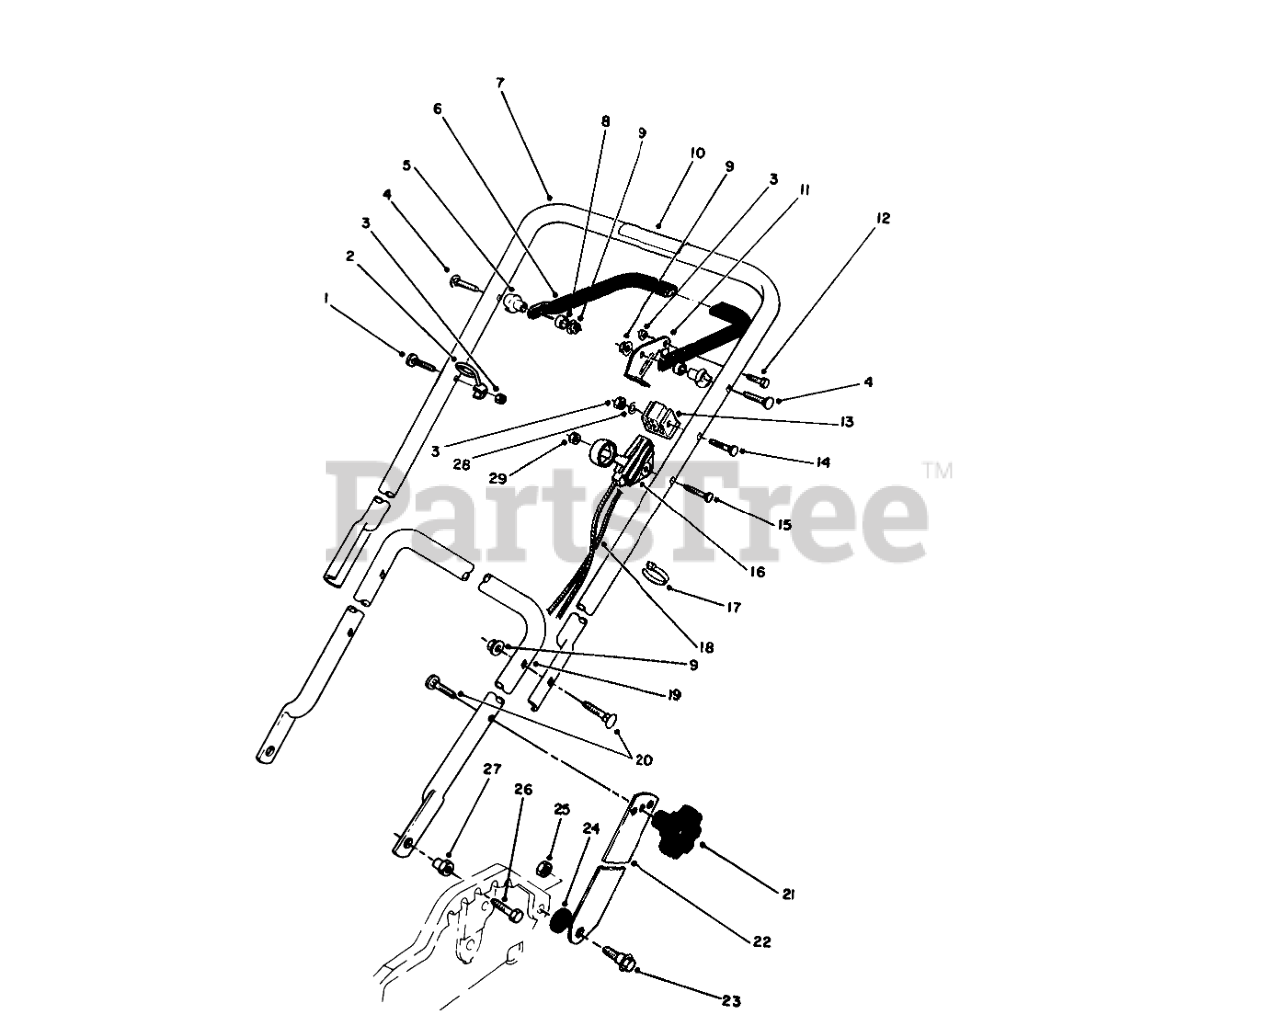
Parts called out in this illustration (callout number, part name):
1	HANDLE SCREW
2	Guide
3	NUT-LOCK, NI
4	5/16-18 X 2 HNDLE SCREW
5	SPACER-SUPPORT
6	Bar-Control
7	Handle-Upper (Incl. Ref. #10)
8	SPACER-NYLON
9	NUT-LOCK, NI
10	DECAL - HANDLE
11	CONTROL LEVER
12	SCREW-HH
13	SUPPORT-CABLE
14	HANDLE SCREW
15	SCREW-HANDLE
16	THROTTLE CONTROL
17	TIE-CABLE
18	BRAKE CABLE
19	LOWER HANDLE
20	SCREW
22	Handle Latch
23	SCREW-SHOULDER
24	SPACER
25	NUT-LOCK, NI
26	SCREW-HH
27	HANDLE PIVOT NUT
28	WASHER-FLAT
29	NUT-LOCK, NI
